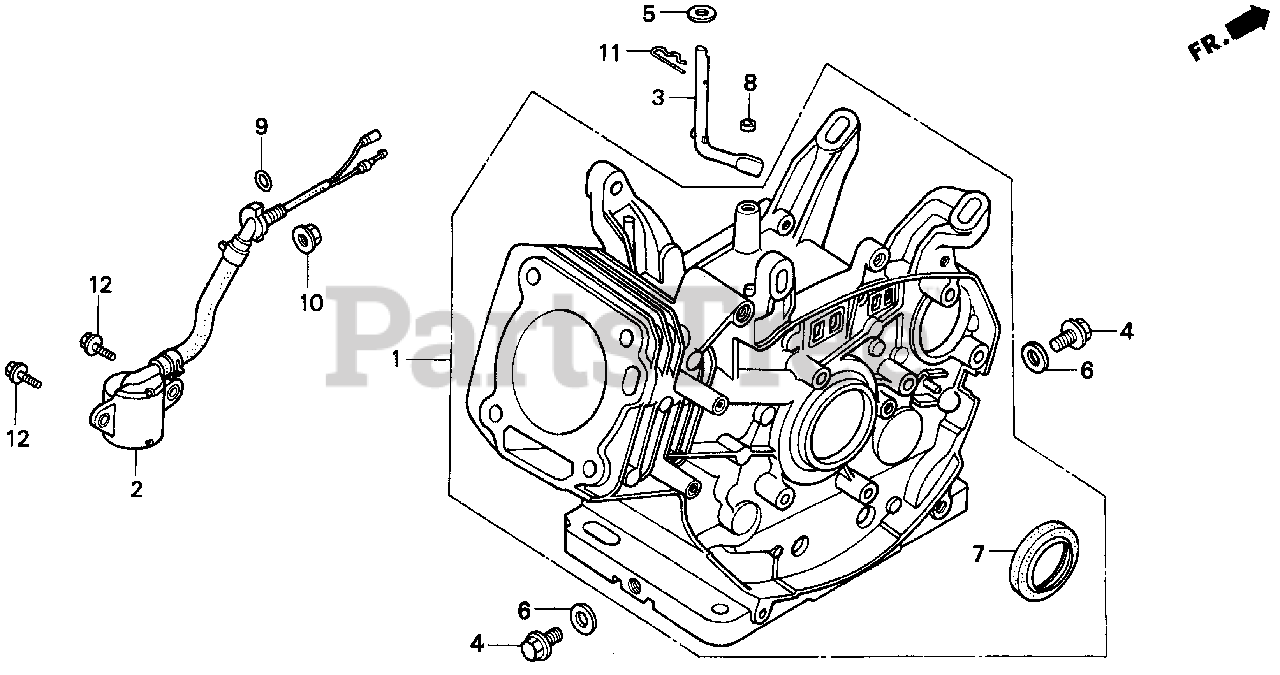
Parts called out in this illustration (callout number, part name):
1	CYLINDER ASSY.
2	SWITCH ASSY., OIL LEVEL
3	SHAFT, GOVERNOR ARM
4	BOLT, DRAIN PLUG
5	WASHER (8.2X17X0.8)
6	WASHER, DRAIN PLUG (12MM)
7	OIL SEAL (30X46X8)
8	OIL SEAL (8X14X5)
9	O-RING (14MM) (ARAI) Use up to Engine SN 2949254.
9	O-RING (14MM) (NOK)
10	NUT, FLANGE (10MM)
11	PIN, LOCK (8MM)
12	BOLT, FLANGE (6X12) Use up to Engine SN 1543277.
